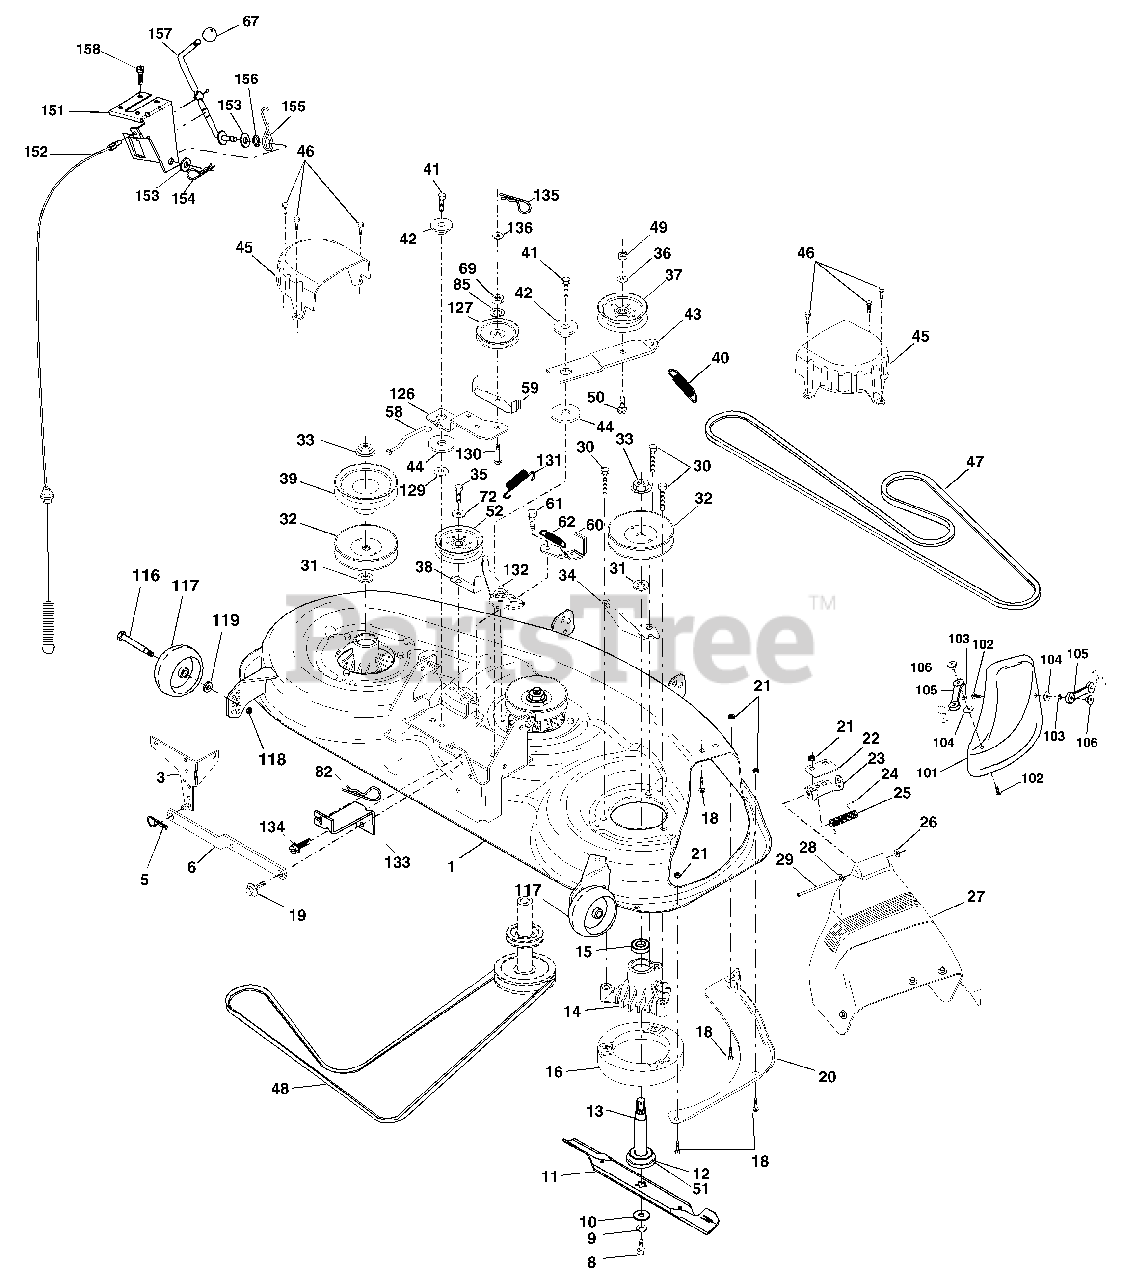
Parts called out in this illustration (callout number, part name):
1	Deck Asm., Mower 46"
3	Bracket Asm., Sway Bar
5	Retainer Spring
6	Arm, Suspension, Rear (Sway Bar)
8	Bolt, Patched 3/8-24 x 1-1/4 Gr. 8
9	Washer, Lock Hvy., Unplated 3/8
10	Washer, Hard Blade, Mower Vented
11	Blade Hi-Perf 46"
12	Bearing, Ball, Mandrel #6204
13	Shaft Asm. w/Lower Bearing
14	Housing, Mandrel
15	Bearing, Ball, Mandrel
16	Stripper, Mower Round
18	Bolt, Carriage 5/16-18 x 5/8
19	Bolt, Hex Head, Shoulder 5/16-18
20	Baffle, Vortex Mower 46"
21	Nut, Crownlock 5/16-18 UNC
22	Stiffiner, Bracket
23	Bracket, Deflector
24	Cap, Sleeve
25	Spring, Torsion, Deflector
26	Nut, Push
27	Shield, Deflector Mower
28	Washer 11/32 x 5/8 x 16 Ga.
29	Rod, Hinge
30	Screw, Thdroll Washer Head
31	Washer, Spacer Mower Vented
32	Pulley, Mandrel
33	Nut, Flg. Top Lock Cntr. 9/16
34	Anchor, Spring Deck 46"
35	Screw, Thdroll 3/8-16 x 1-3/4 Tytt
37	Pulley, Idler, Flat
38	Keeper, Belt, Idler
39	Pulley, Idler, Driven
40	Spring, Secondary 44/46/50 Vent
41	Screw 3/8-16 x 1-1/4
42	Spacer, Retainer
43	Arm, Idler Secondary
44	Washer, Hardened
45	Cover, Mandrel Deck
46	Screw, Thdroll. 1/4-20 x 5/8
47	V-Belt, Mower, Secondary
48	V-Belt, Mower, Primary
49	Nut, Crownlock 3/8-16 UNC
50	Bolt, Carriage 3/8-16 x 1-1/2 Gr. 5
51	Washer Felt
52	Pulley Idler Flat
58	Rod Brake 46"
59	Guide Bolt 46" Mower Dr
60	Arm Asm Brake 46"
61	Bolt Shld 5/16-18
62	Spring Return
67	Knob Rd 3/8-16 Plstc Thds Blk
69	Nut Hex Jam 3/8-16 Unc
72	Washer 13/32 x 1 x 16 Ga.
82	Retainer Spring
85	Washer Lock 3/8
101	Cover Mulcher 46" Black
102	Screw Truss Hd Phil 10-24 x 5/8
103	Washer Lock #10
104	Washer #10
105	Latch Asm Bagger
106	Nut Weld .327/.304 #10-24
116	Bolt, Shoulder
117	Gauge Wheel
118	Nut, Centerlock 3/8-16 UNC
119	Washer 3/8 x 7/8 x 14 Ga.
126	Arm, Idler, Primary Deck 46"
127	Pulley, Idler, V-Groove Dim. 4.25
129	Washer 13/32 x 2-3/8 x 8 Ga
130	Bolt Carriage Idler
131	Spring Return Idler
132	Arm Spring Brake Mower
133	Bracket Anchor Cable 46"
134	Screw Thdrol 5/16-18 x 3/4
135	Retainer Spring Yellow
136	Washer 9/32 x 3/4 x 16 Ga
151	Bracket Clutch Cable
152	Clutch Cable 38"/46"
153	Washer Flat 3/8" Type B
154	Spring Retainer
155	Spring Retension Q
156	SPacer Clutch Cable
157	Rod Clutch Cable 3/8"
158	Screw Hex Thd Cut 1/4-20 x 5/8
